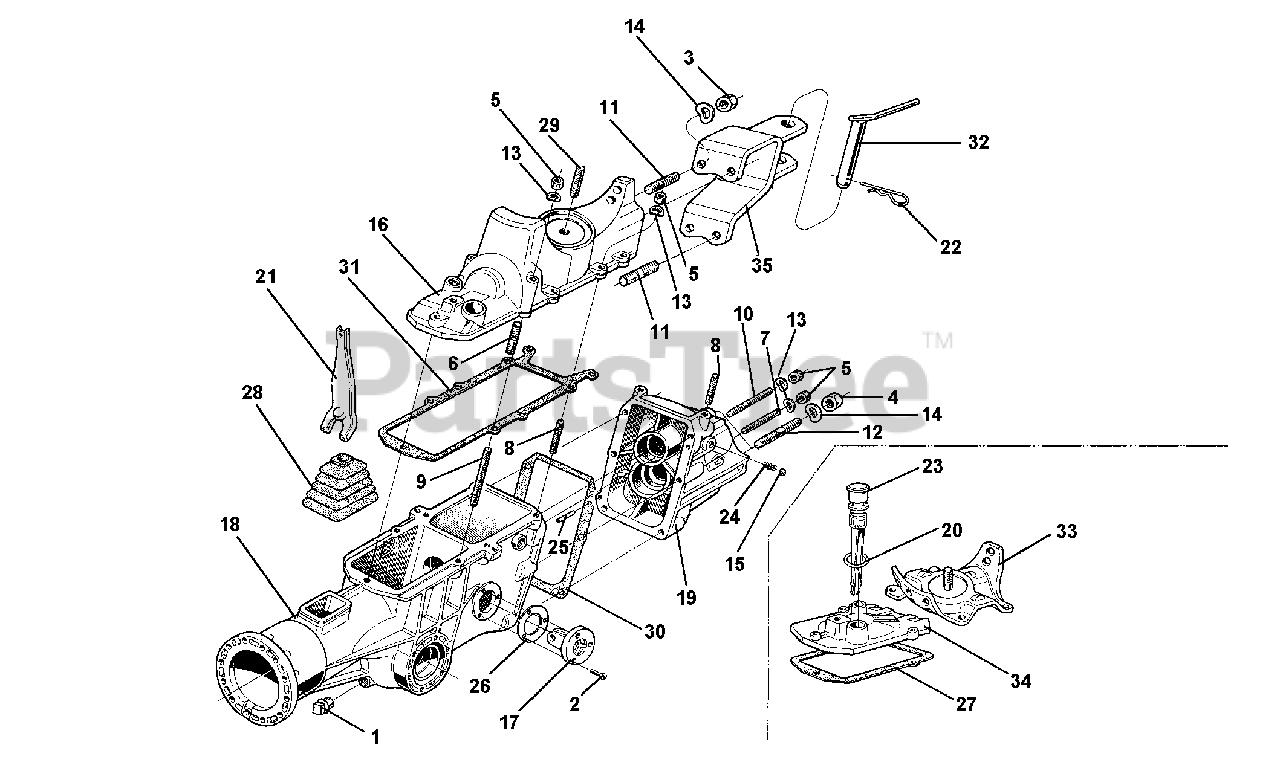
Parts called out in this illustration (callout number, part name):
1	PLUG 1/4 GAS
2	SCREW TSV M6 X 16 UNI 260-5S
4	NUT M12 X 1.25 UNI 5587 6S
5	NUT, SELF LOCKING M8
6	STUD M8 X 46 X 20 X 12
7	STUD M8 X 58 X 16 X 16
8	STUD M8 X 40 X 14 X 14
10	STUD M8 X 70 X 16 X 16 8G
13	WASHER, LOCK 8.4
14	WASHER, LOCK 13
15	BALL 15/32 RIV RB-11.906
16	SYNCHRONIZED PTO COVER 745
17	FLANGE, REVERSE SPEED
18	GEARBOX 745 / 606-605
20	RUBBER RING
21	CLUTCH LEVER
23	CAP, WITH MEASURING ROD
25	PARALLEL PIN D 6 X 20
27	GASKET, COVER
30	COVER GASKET
31	COVER GASKET
33	CAP WITH HOLE D.13
34	COVER DIFFERENTIAL
35	TOW COUPLING
